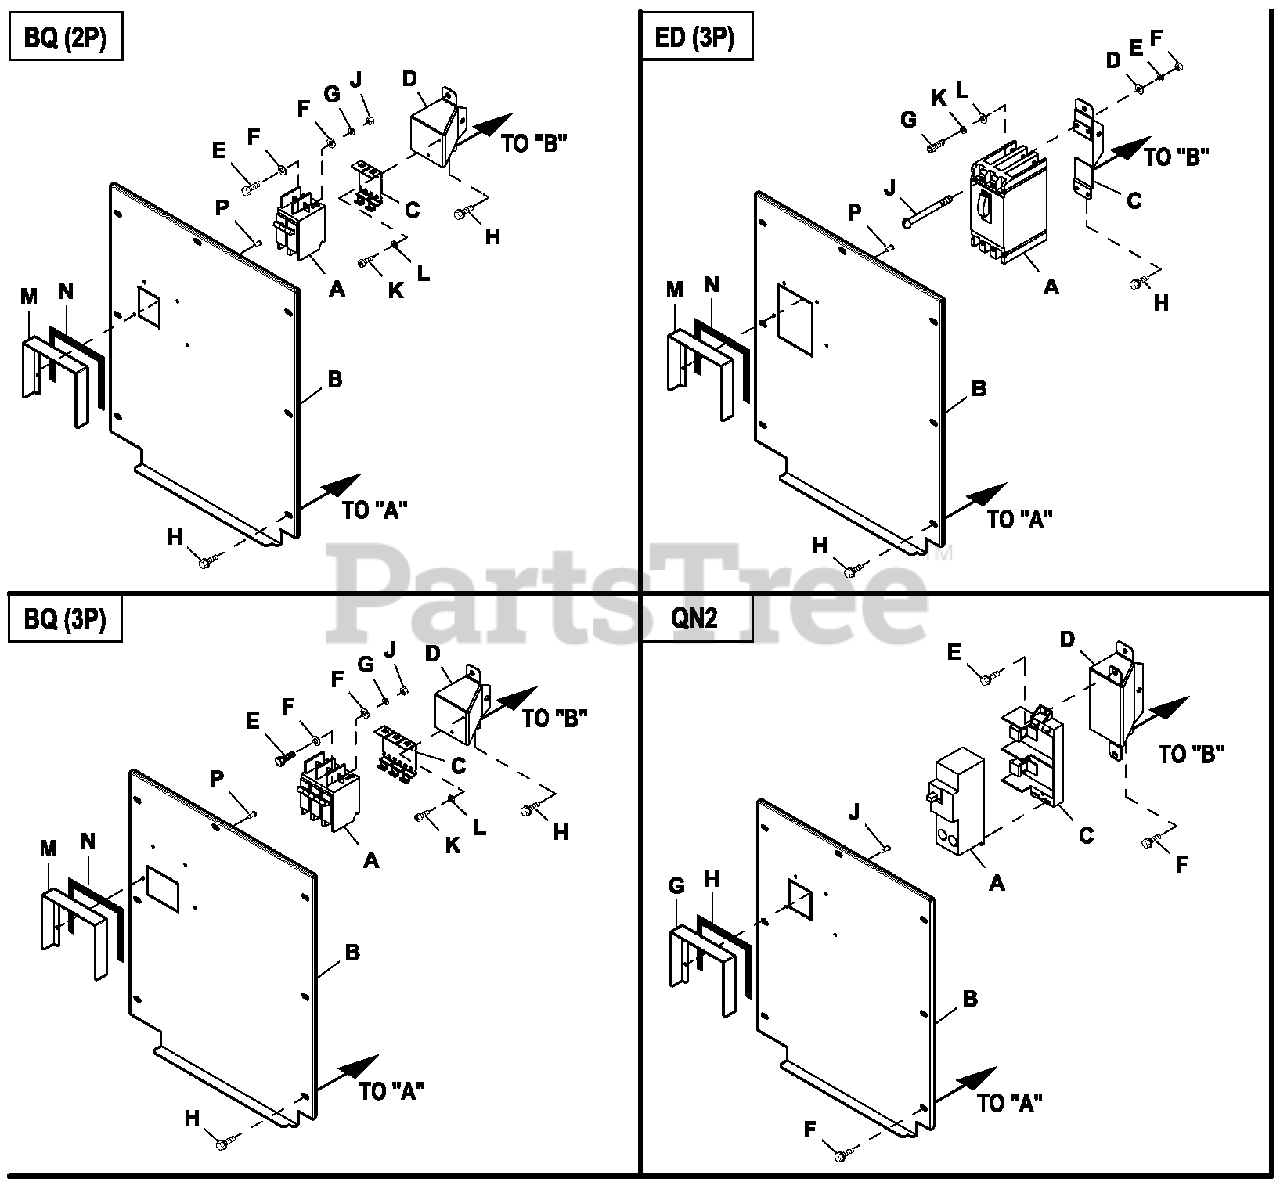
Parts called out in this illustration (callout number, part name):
A	CB 0090A 2P 240V S BQ2 LL
B	COVER CB S BQ2C1 CONBOX
C	BRKT CB MTG BACK
D	CIRCUIT BREAKER SUPPORT (BQ)
E	SCREW HHC M5-0.8 X 20 G8.8
F	WASHER FLAT #10 ZINC
G	WASHER LOCK M5
H	SCREW HWHT M6-1 X 16 N WA Z/JS
J	N UT HEX M5-0.8 G8 CLEAR ZIN C
K	SCREW PHTT M4-0.7 X 8 ZP
L	WASHER LOCK#8-M4
M	SHIELD CB HA N DLE CO N BOX
N	TAPE ELEC 1/2 FOAM
P	RIVET POP .125 X .275 SS
A	CB 0050A 3P 480V S ED4 LL
B	CB 0125A3P 480V S ED4 LL
C	COVER CB S ED3C1 CONBOX
D	CIRCUIT BREAKER SUPPORT (ED)
E	WASHER FLAT #8 ZIN C
F	WASHER LOCK#8-M4
G	N UT HEX #8-32 STEEL
H	SCREW SHC 1/4-28 X 3/4 G8.8 NZ
J	SCREW HWHT M6-1 X 16 N WA Z/JS
K	SCREW RHM #8-32X4-1/2
L	WASHER LOCK M6-1/4
M	WASHER-STEP 1/2ODX9/32ID BRASS
N	SHIELD CB HA N DLE CO N BOX
P	TAPE ELEC 1/2 FOAM
A	CB 0150A2P 240V S Q N 2 LL
B	COVER CB S QN2 C1 CONBOX
C	BASE, Q N CIRCUIT BREAKER
D	BREAKER SUPPORT BRACKET 30KW
E	SCREW HHTT M5-0.8 X 10 BP
F	SCREW HWHT M6-1 X 16 N WA Z/JS
G	SHIELD CB HA N DLE CO N BOX
H	TAPE ELEC 1/2 FOAM
J	RIVET POP .125 X .2
